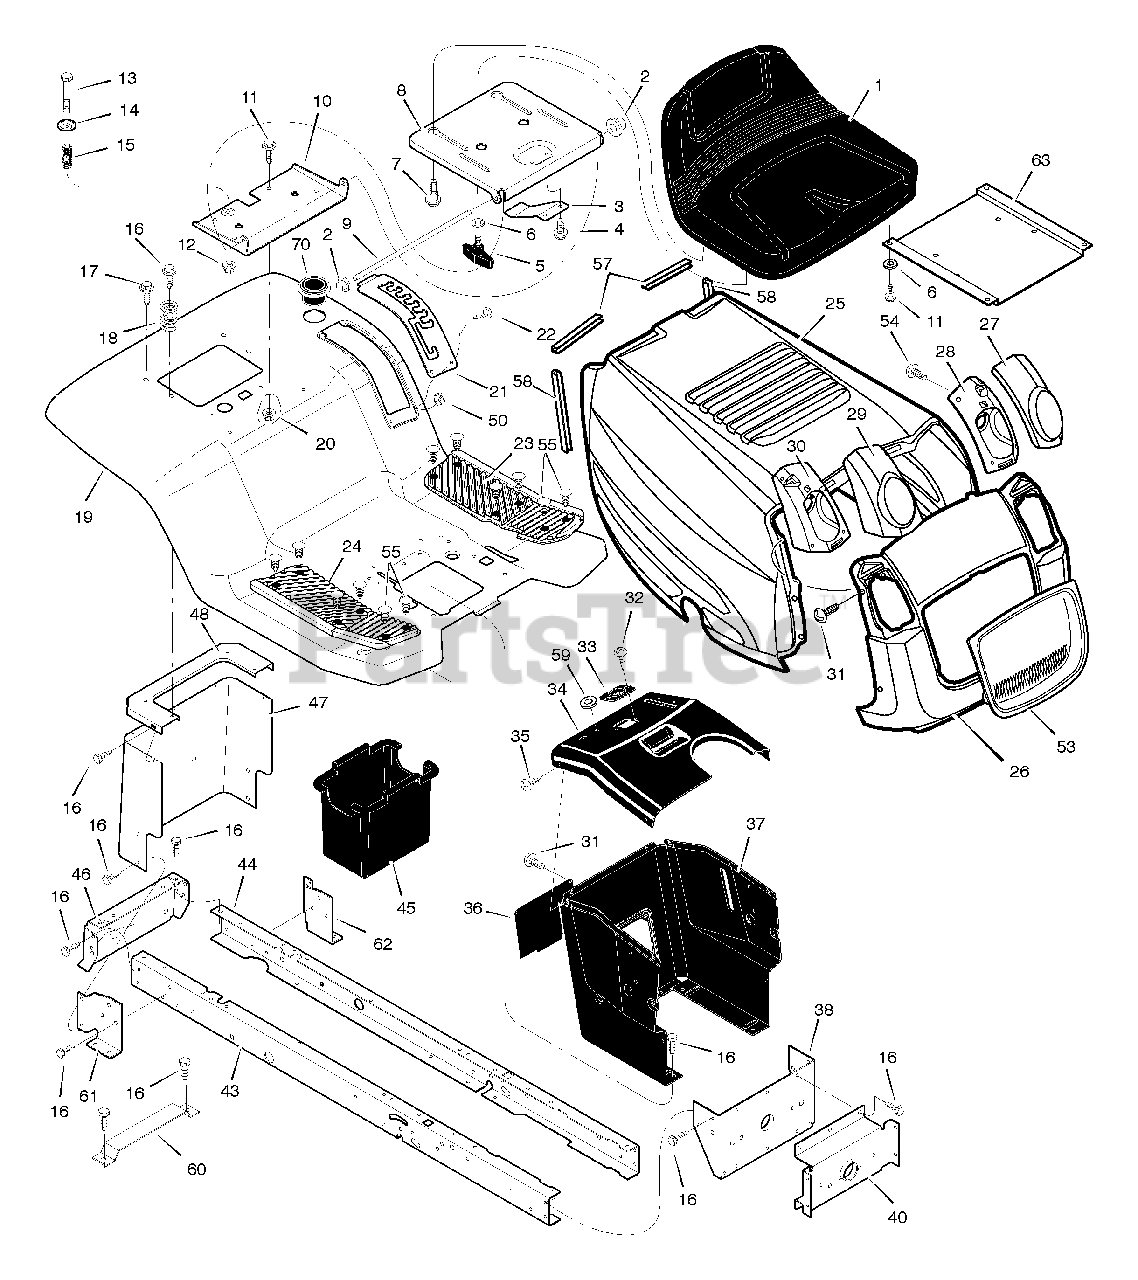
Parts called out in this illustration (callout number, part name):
2	Cap, Push 0n
5	Bolt, Wing
6	Washer
7	Bolt, Shoulder
8	Support, Seat
9	Rod, Pivot
10	Bracket, Pivot
11	Bolt
13	Bolt, Shoulder
15	Spring
19	Deck, Seat
20	Nut
21	Plate, Index
22	Screw
23	Mat, Left
24	Mat, Right
25	Hood
27	Lens, Left
28	Housing, Left Headlamp
29	Lens, Right
30	Housing, Right Headlamp
31	Screw
33	Bearing, Steering
34	Dash
36	Panel, Access
37	Support, Dash
38	Bracket, Rear Hanger
40	Axle, Hanger
43	Frame, Right
44	Frame, Left
45	Container, Battery
46	Plate, Hitch
47	Plate, Rear
48	Top, Rear Plate
53	Insert, Grille
54	Screw
55	Fastener, Panel
57	Trim, Hood (3.75")
58	Trim, Hood (6.5")
59	Grommet, Parking Brake
60	Bracket, Support
61	Bracket, Right Transaxle
62	Bracket, Left Transaxle
63	Plate, Seat
70	Holder, Cup
